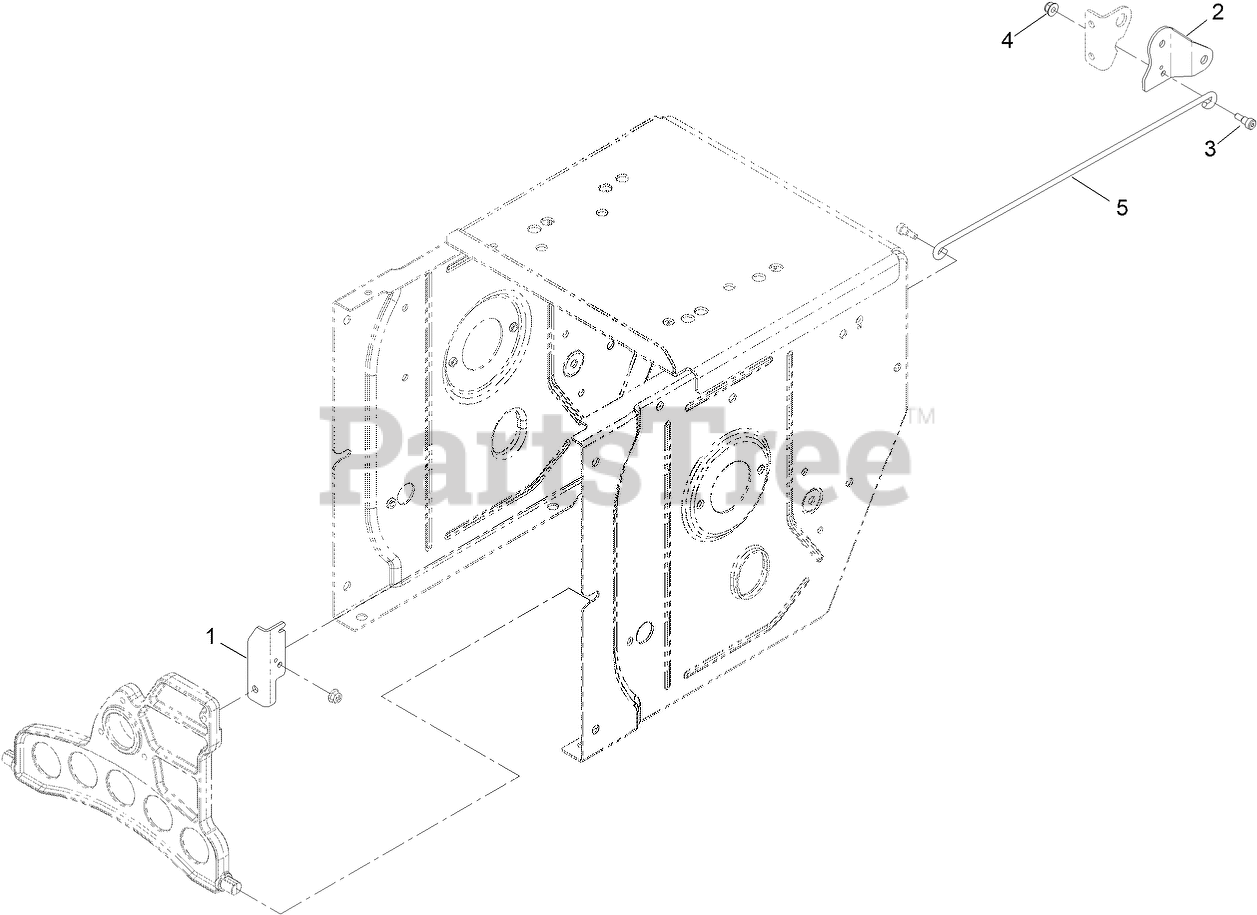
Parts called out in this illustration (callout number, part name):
1	BKT-TRACTION PLATE
2	BELLCRANK-DRIVE
3	SCREW-SHOULDER
4	NUT-HF
5	LINK-TRACTION, HD
